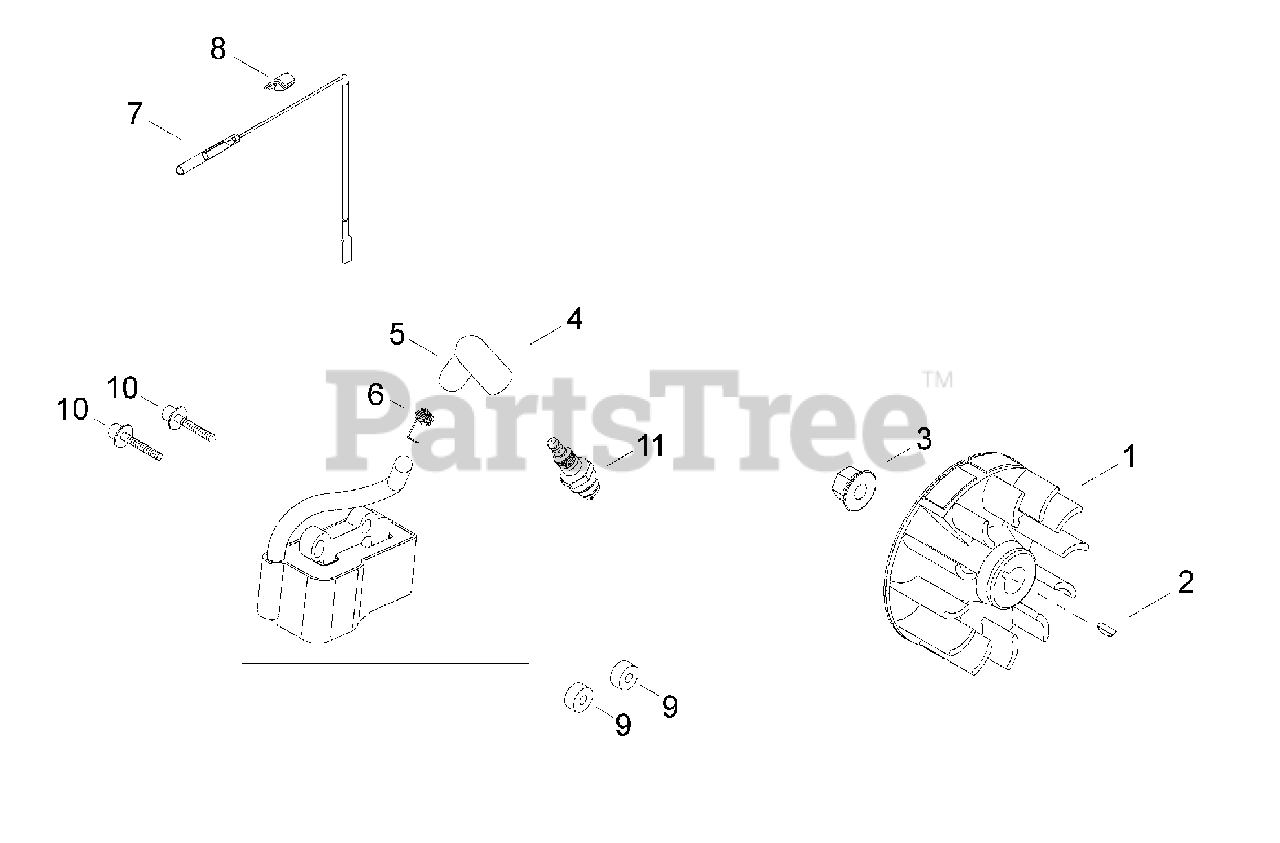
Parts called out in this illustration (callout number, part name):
1	FLYWHEEL
2	KEY - 3X10
3	NUT - 8
4	IGNITION COIL ASSY
5	CAP, SPARK PLUG
6	TERMINAL, SPARK PLUG CAP
7	LEAD - IGNITION
8	GROMMET
9	INSULATOR
10	SCREW - 4X26
11	SPARK PLUG -- CMR-5H
